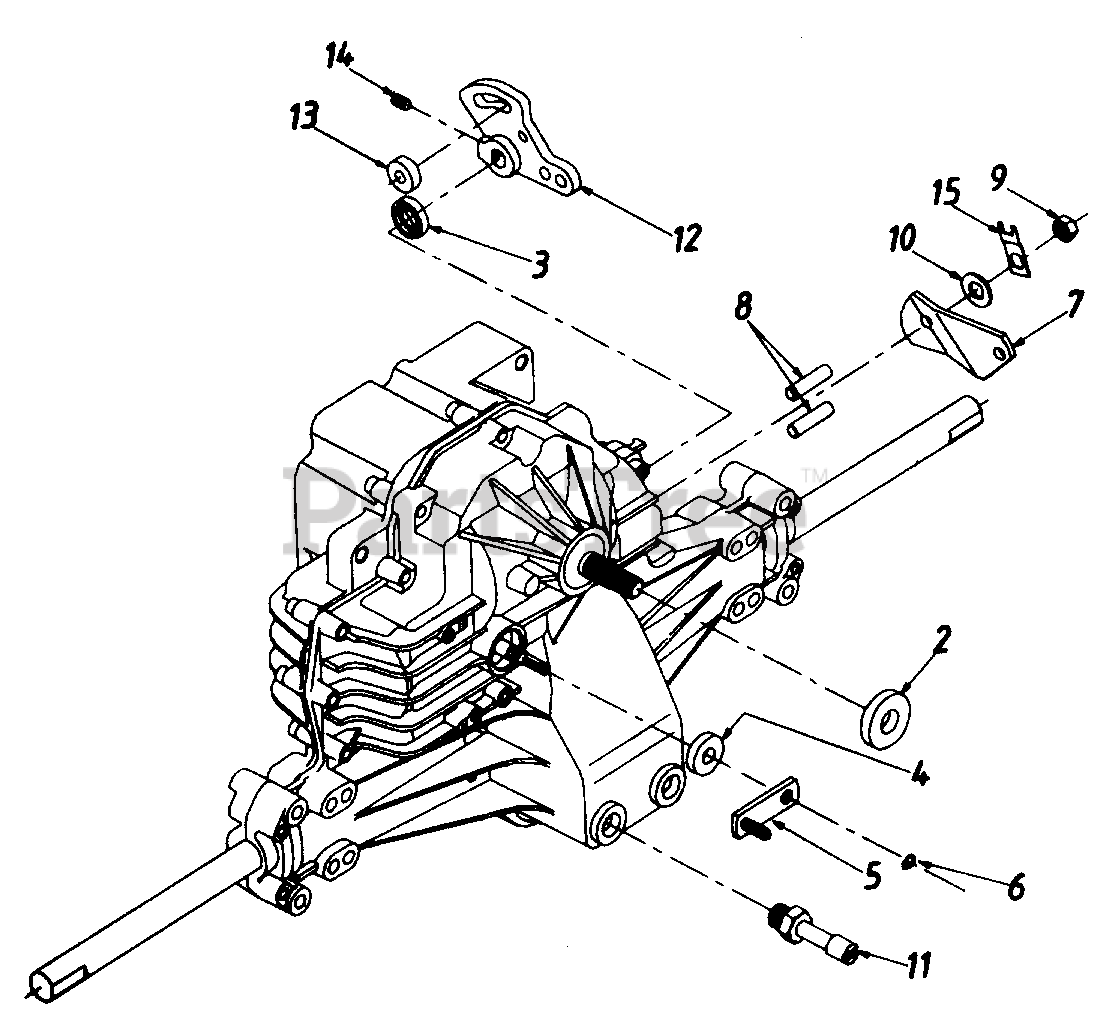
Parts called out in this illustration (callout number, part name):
2	Seal - Lip
3	Seal - Lip
4	Seal - Lip 10x 25X7
5	Arm - Bypass
6	Ring - Retaining
7	Arm - Actuating
8	Pin - Actuating
9	Nut - Hex Lock 5/16-24 UNJC
10	Washer 7/16" x 7/8" x .060"
11	Breather Ass'y.
12	Arm - Control
13	Puck - Dampener
14	Set Screw
15	Strap, Locking
